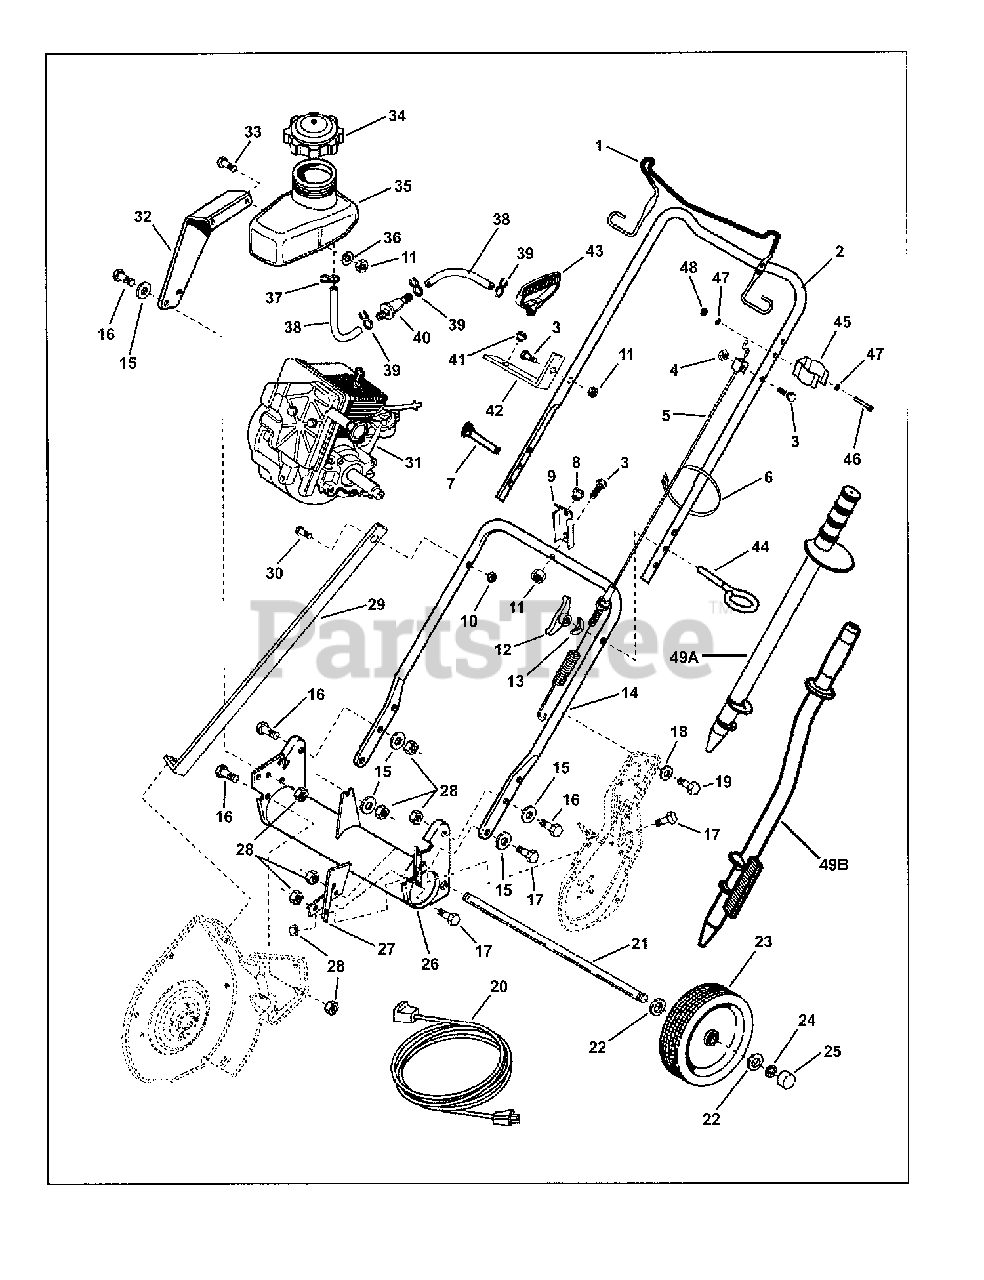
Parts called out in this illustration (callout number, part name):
1	HANDLE, Auger Control
2	HANDLE, Upper
3	CAPSCREW, Hex Head, 1/4-20 x 1-1/4"
4	NUT, Hex Centerlock, 1/4-20
5	CABLE, Auger Control
6	TIE, Self Locking
7	BOLT, 5/16-18 x 1-3/4" Round Head
8	SNAP BUSHING, 3/8
9	BRACKET, Chute Rotator Rod
10	NUT, Hex Lock, #10-24
11	NUT, Hex Lock Esna, 1/4-20
12	KNOB, Wing (5/16-18 Black)
13	WASHER, Curved, 5/16"
14	HANDLE, Lower
15	WASHER, 5/16 I.D. x 3/4 O.D. Flat
16	CAPSCREW, Hex Head, 5/16-18 x 3/4"
17	CAPSCREW, Hex Head, 5/16-18 x 1"
18	LOCKWASHER, 5/16"
19	CAPSCREW, Hex Head, 5/16-18 x 3/4"
20	CORD, Extension (Electric Start Models)
21	SHAFT, Axle
22	WASHER, .41 I.D. x .87 O.D.
23	TIRE, Semi-pneumatic
24	RING, Retainer, Ext., #37
25	CAP, Hub
26	WELDMENT, Frame Assy.
27	BRACKET, Reinforcement
28	NUT, Hex Lock ESNA Light, 5/16-18
29	STRAP, Support
30	SCREW, Hex Washer Head, #10-24 x 1-1/4"
31	* ENGINE, Manual Start Mod HSK850-8319D
31	* ENGINE, Electric Start Mod HSK850-8325D
32	BRACKET, Fuel Tank
33	CAPSCREW, Hex Head, 1/4-20 x 3/4"
34	CAP, Fuel Tank
35	TANK, Fuel
36	WASHER, .27 I.D. x .62 O.D.
37	HOSE CLAMP (worm type)
38	HOSE, Fuel, 5-1/2" long
38	HOSE, Fuel, 8-1/2" long
39	HOSE CLAMP, Wire Form
40	FILTER, Fuel
41	SNAP BUSHING, 1/4"
42	BRACKET, Starter Handle
43	HANDLE, Start (Mitten)
44	HOLDER, Snostik- Lower (5/16-18 thread)
45	HOLDER, Snostik- Upper
46	SCREW, #10-24 x 1-1/4" Hex Head Cap
47	WASHER, #10 Internal Tooth Lock
48	NUT, #10-24 Hex Center Lock
49A	SNOW STICK
49B	SNOW STICK w/Brush
